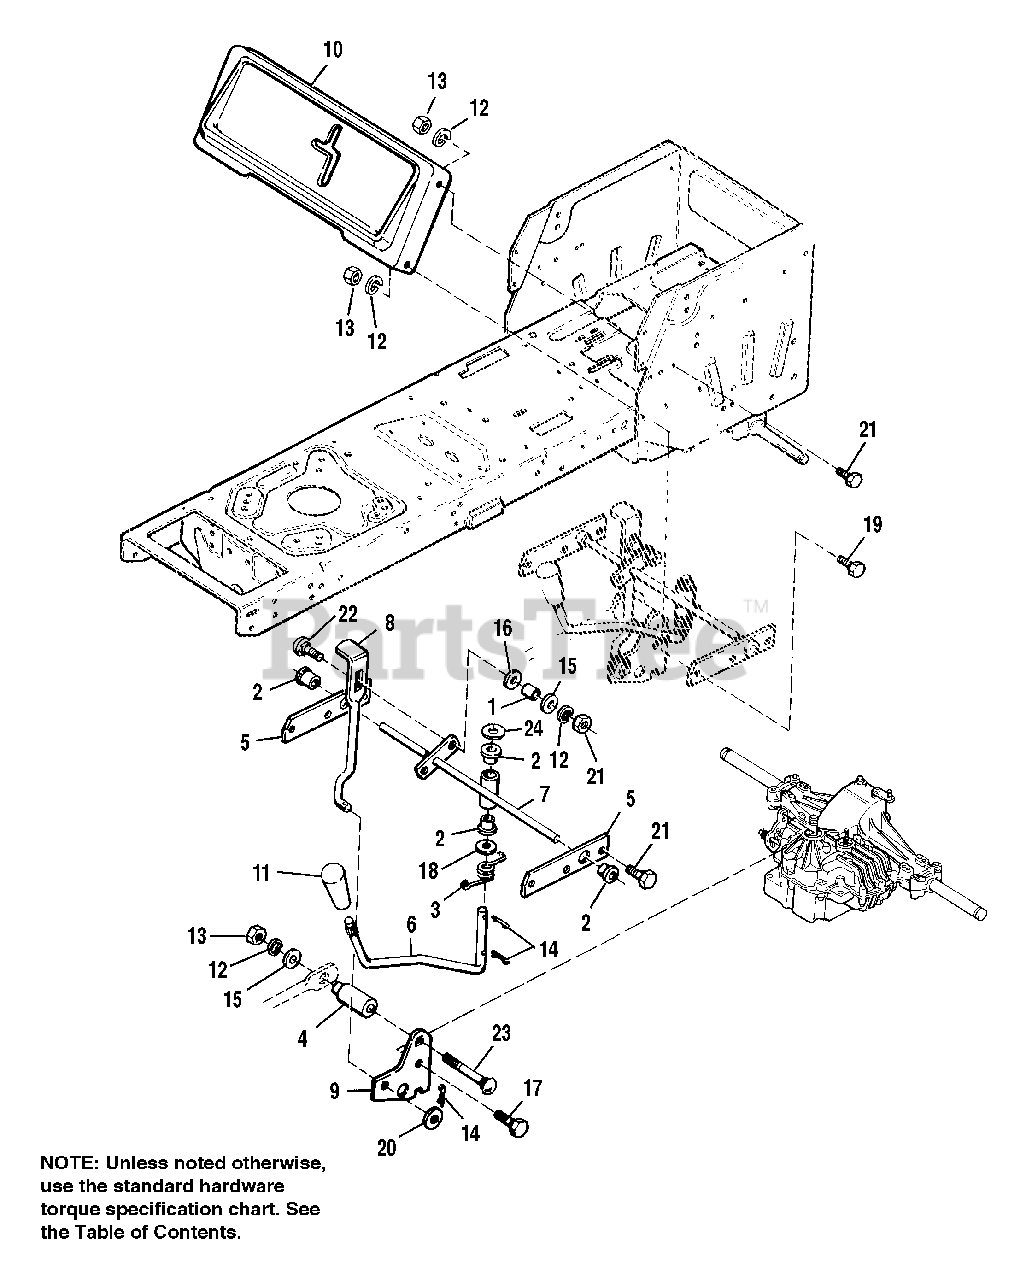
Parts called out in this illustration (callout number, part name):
3	SPRING, Torsion
5	BRACE, Shift Panel
6	ROD, Shift
7	SHIFT ROD ASSY.
8	ROD, Control
9	CONTROL LEVER
10	PANEL, Shift
11	KNOB, Large
12	LOCKWASHER, Spring, 5/16
13	NUT, Hex, 5/16-18
14	COTTER PIN, 15/16 X 3/4
15	WASHER, Plain, 11/32 x 3/4 x 1/16
16	WASHER, 11/32 x 1 x 1/8
17	CAPSCREW, Hex Hd., 5/16-18 x 1
18	WASHER, Plain, 1/2 x 1-1/4 x 5/64
19	SCREW, Taptite, 1/4-20 x 1/2
20	WASHER, Plain, 13/32 x 7/8 x 5/64
21	SCREW, Taptite, 5/16-18 x 1/2
22	CARRIAGE BOLT, 5/16-18 x 1
23	CARRIAGE BOLT, 5/16-18 x 1-1/2
24	WASHER, Plain, 1/2 x 1 x 3/32
